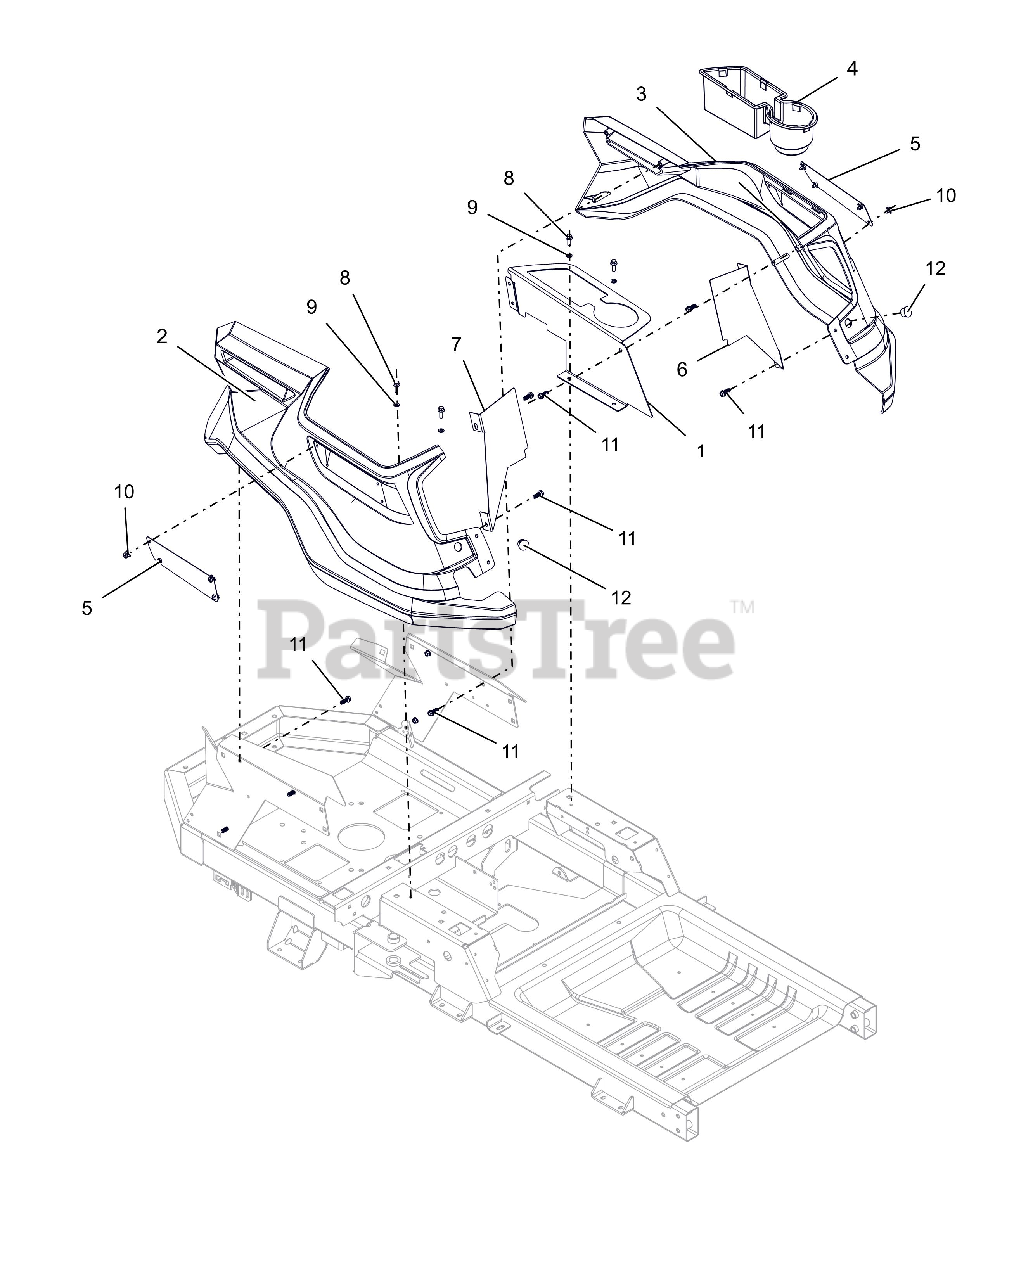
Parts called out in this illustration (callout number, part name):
1	PANEL, LEFT SIDE FENDER MOUNT
2	FENDER, RH IKON
3	FENDER, LH IKON
4	INSERT, CUP/STORAGE HOLDER
5	PLATE, ARIENS NAME
6	PLATE, LH BLOCKER
7	PLATE, RH BLOCKER
8	BLT,HEX-FLG .25-20X.75 G5 BFP
9	@WSHR-LK .25X.062 REG YWZC
10	RIVET, PLASTIC .195 DIA.
11	SCR-.312X.75 #14H H/W/H H/L CZ
12	PLUG, HOLE .75 (BLACK)
